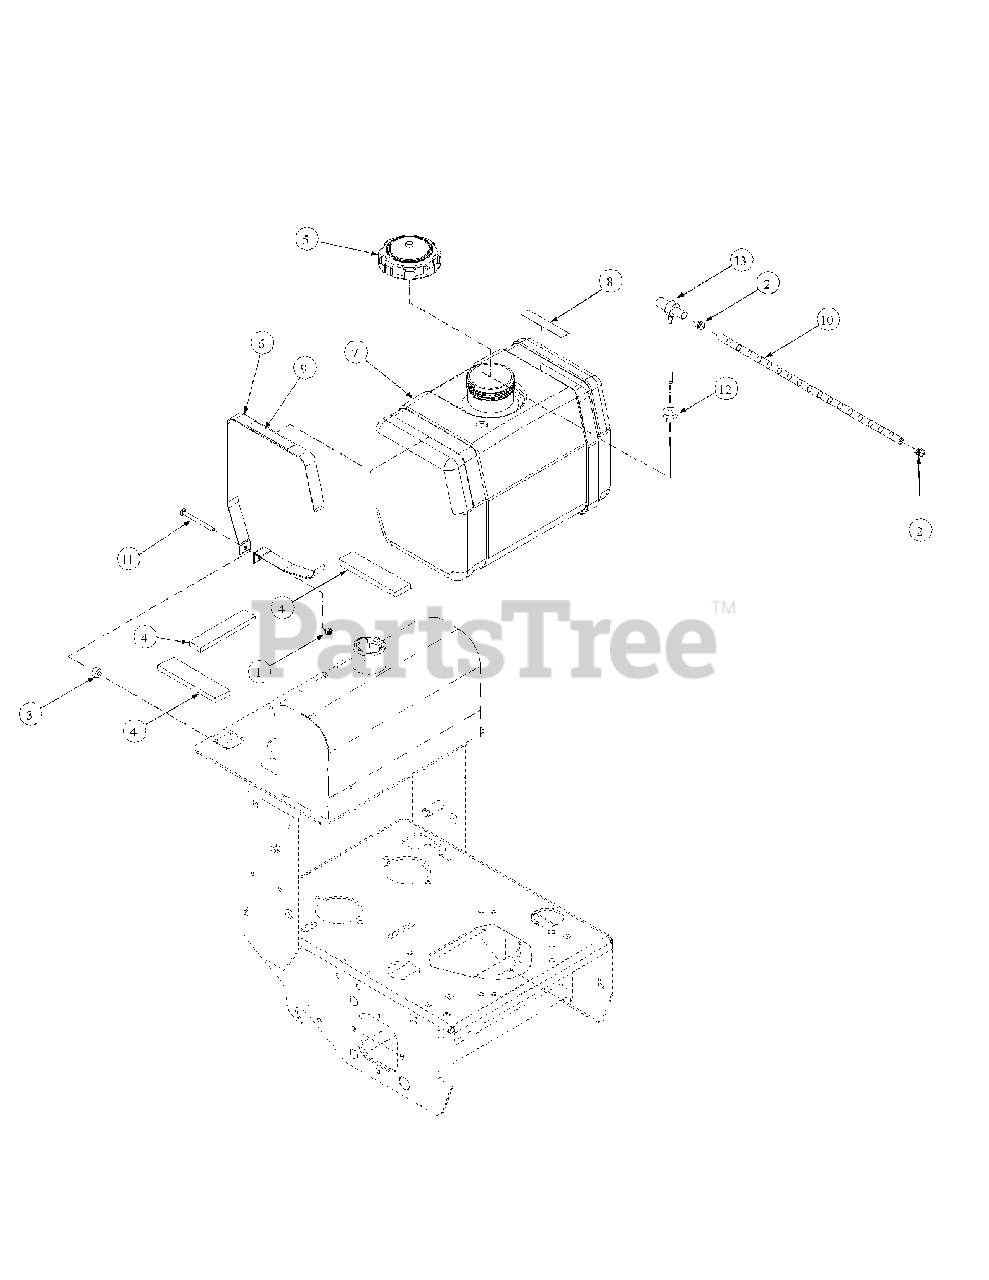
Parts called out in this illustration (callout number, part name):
1	Lock Nut, Nylon Insert, 1/4-20
2	Uni-Clamp
4	Stop Pad, Rubber
5	Fuel Cap, 3.5
6	Fuel Tank Strap
7	Fuel Tank
8	Mower Warning Label, Turn off Engine
9	Mower Instruction Label, Fuel Valve
10	Fuel Hose, 18"
11	Carriage Bolt, 1/4-20 x 3.00
12	Grommet Fuel Tank
13	Shutoff Valve
